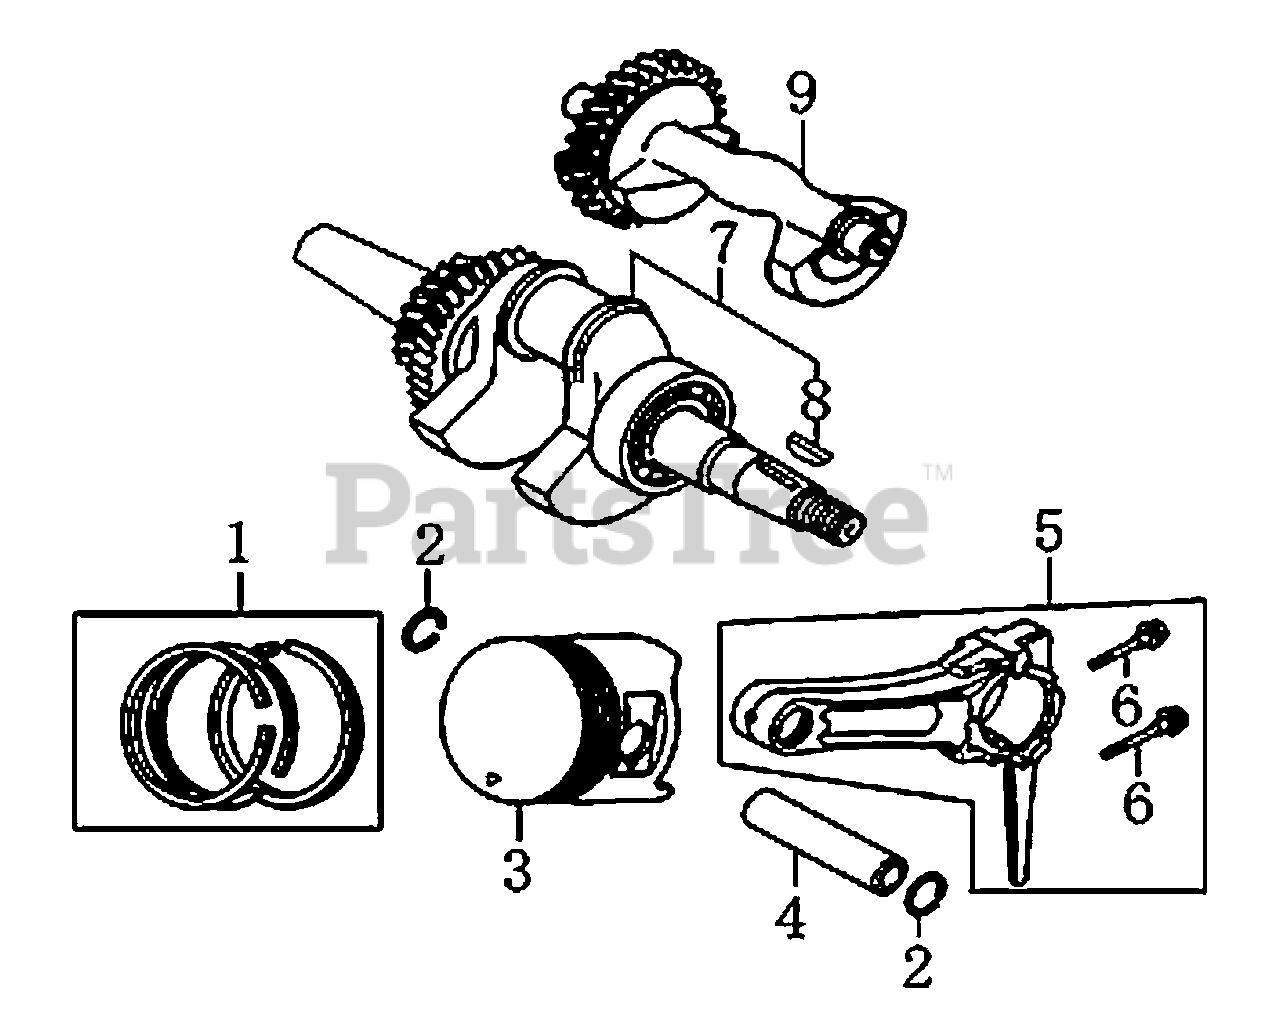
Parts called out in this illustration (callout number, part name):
1	RING SET'PISTON
2	CLIP'PISTON PIN
4	PIN'PISTON
5	CONNECTING ROD ASSY
6	BOLT'CONNECTING ROD
7	CRANKSHAFT ASSY
8	KEY'SPECIAL WOODRUFF
9	WEIGHT'BALANCER
